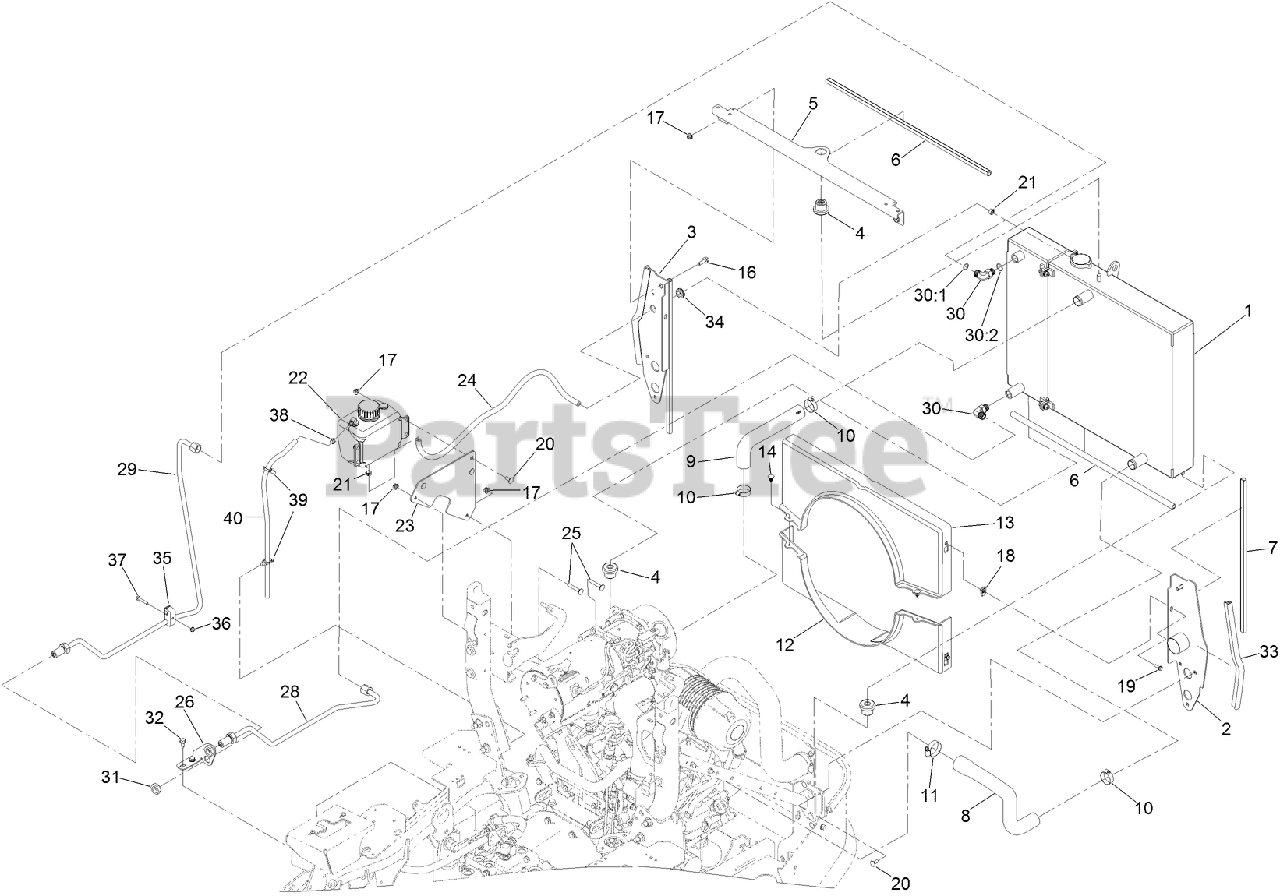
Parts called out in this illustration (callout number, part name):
1	COOLING ASM
2	SUPPORT-RADIATOR, LH
3	SUPPORT-RADIATOR, RH
4	MOUNT-ISOLATOR
5	BRACKET-COOLING, TOP
6	SEAL-BULB
7	SEAL-BULB
8	HOSE-RADIATOR, LOWER
9	HOSE-RADIATOR, UPPER
10	CLAMP-HOSE
11	CLAMP-HOSE
12	SHROUD-BOTTOM
13	SHROUD-TOP
14	PLUG-PLASTIC
16	SCREW-HHF
17	NUT-HF, NI
19	SCREW-HWH
20	SCREW-CARR
21	CLAMP-HOSE
22	TANK-OVERFLOW (W/CAP)
23	BRACKET-BOTTLE
25	BOLT-CARR
26	BRACKET-BULKHEAD
28	HYDRAULIC TUBE ASM
29	HYDRAULIC TUBE ASM
30	FITTING-ELBOW, 90 DEG
30:1	O-RING
30:2	O-RING
31	NUT-BULKHEAD
32	SCREW-HWHTF
33	SEAL-BULB
34	GROMMET
35	CLAMP-TWIN
36	NUT-HF
37	SCREW-HH
38	CLAMP-HOSE
39	CLIP-TIE
40	HOSE-FUEL
